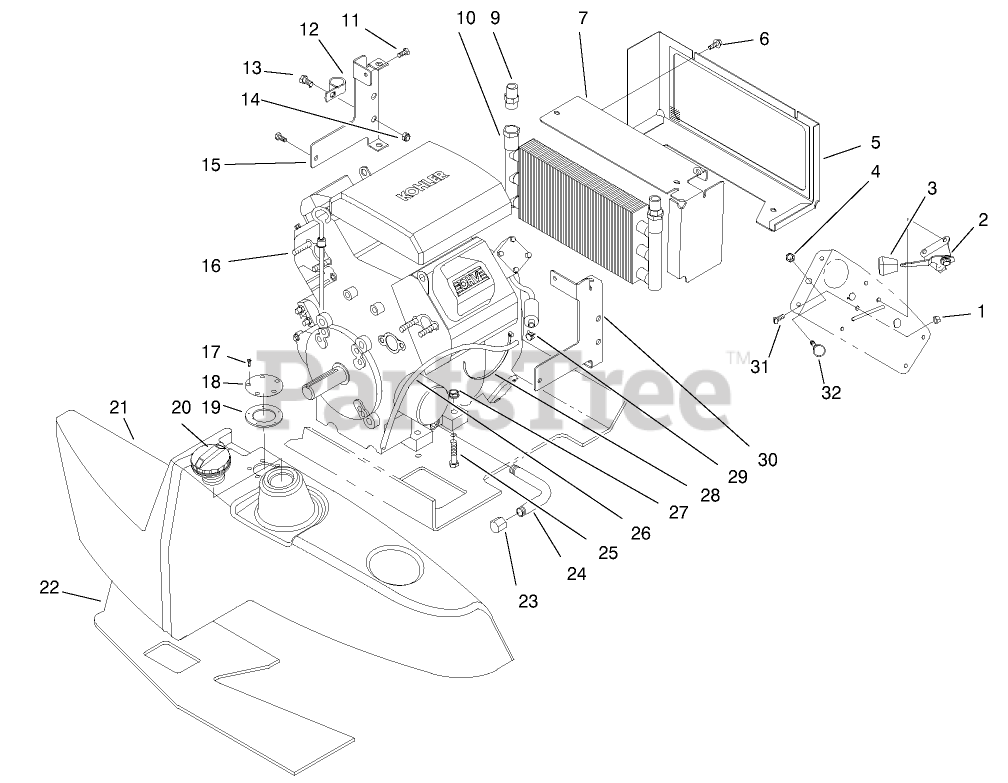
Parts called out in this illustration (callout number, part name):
1	NUT-LOCK, NI
2	THROTTLE CONTROL ASM
4	NUT-HJ
5	COOLER SHROUD ASM
6	SCREW-HHF
7	Cooler Shroud ASM
9	FITTING-ADAPTER
10	COOLER ASM
11	SCREW-HWH
12	CLAMP-R
13	SCREW-HH
14	NUT-LOCK, NI
15	Bracket-Rear
17	SCREW-PPH
18	COVER-FUEL TANK OPENING
19	GASKET
20	CAP-FUEL
21	FUEL TANK ASM
22	FOAM-TANK, FUEL
23	CAP-PIPE
24	TUBE-DRAIN, OIL
25	SCREW-HH
26	HOSE - GAS
27	NUT-LOCK, NI
28	TIE-CABLE
29	CLAMP-HOSE
30	Bracket-Front
31	SCREW-PPH
32	CONTROL-CHOKE
